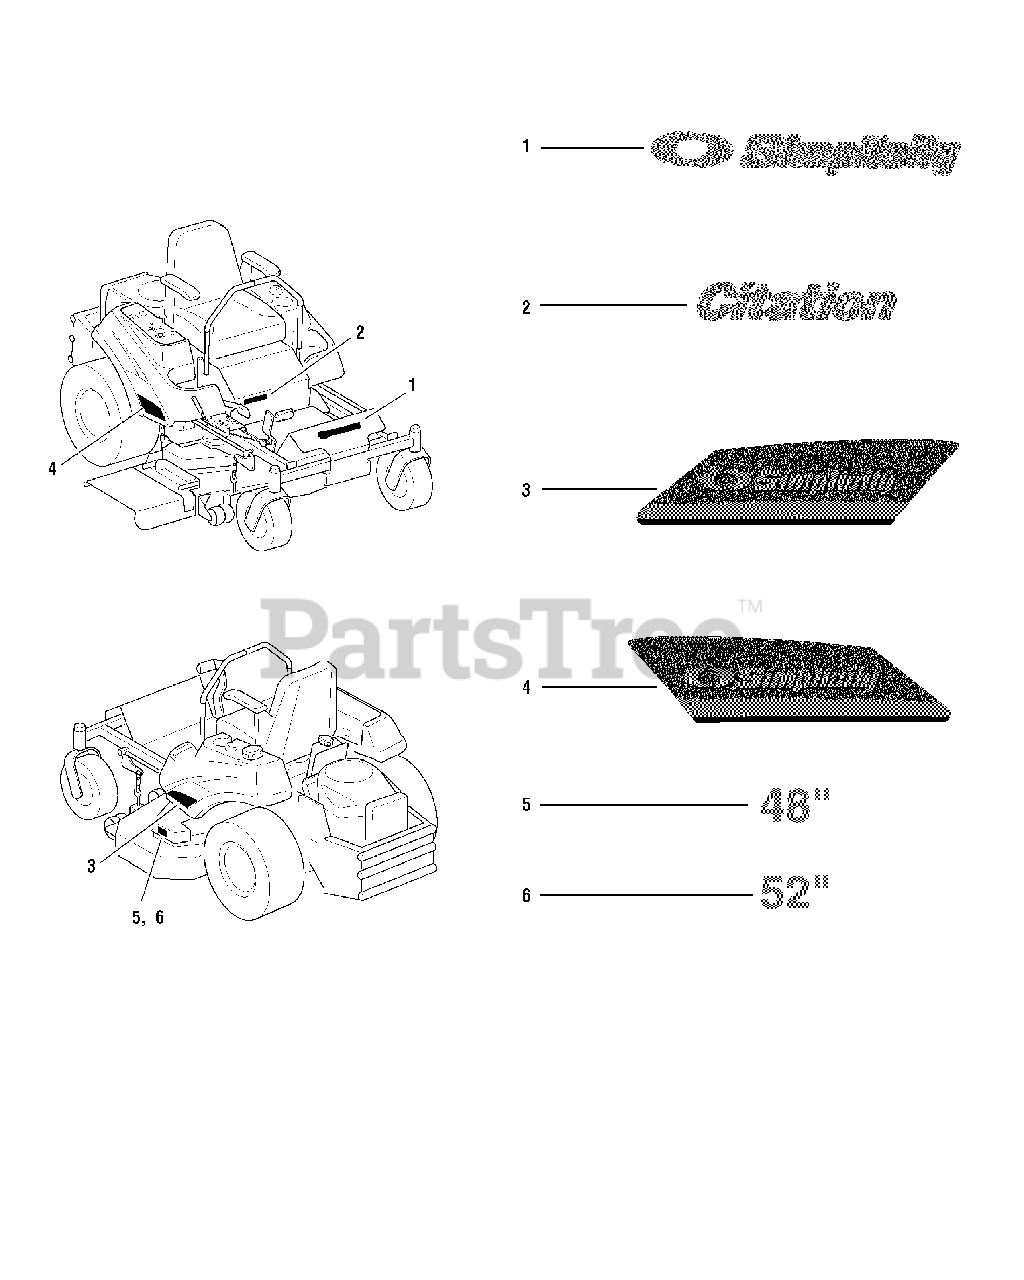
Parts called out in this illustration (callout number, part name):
1	DECAL, Simplicity Logo
2	DECAL, Citation
3	DECAL, Badge, RH
4	DECAL, Badge, LH
